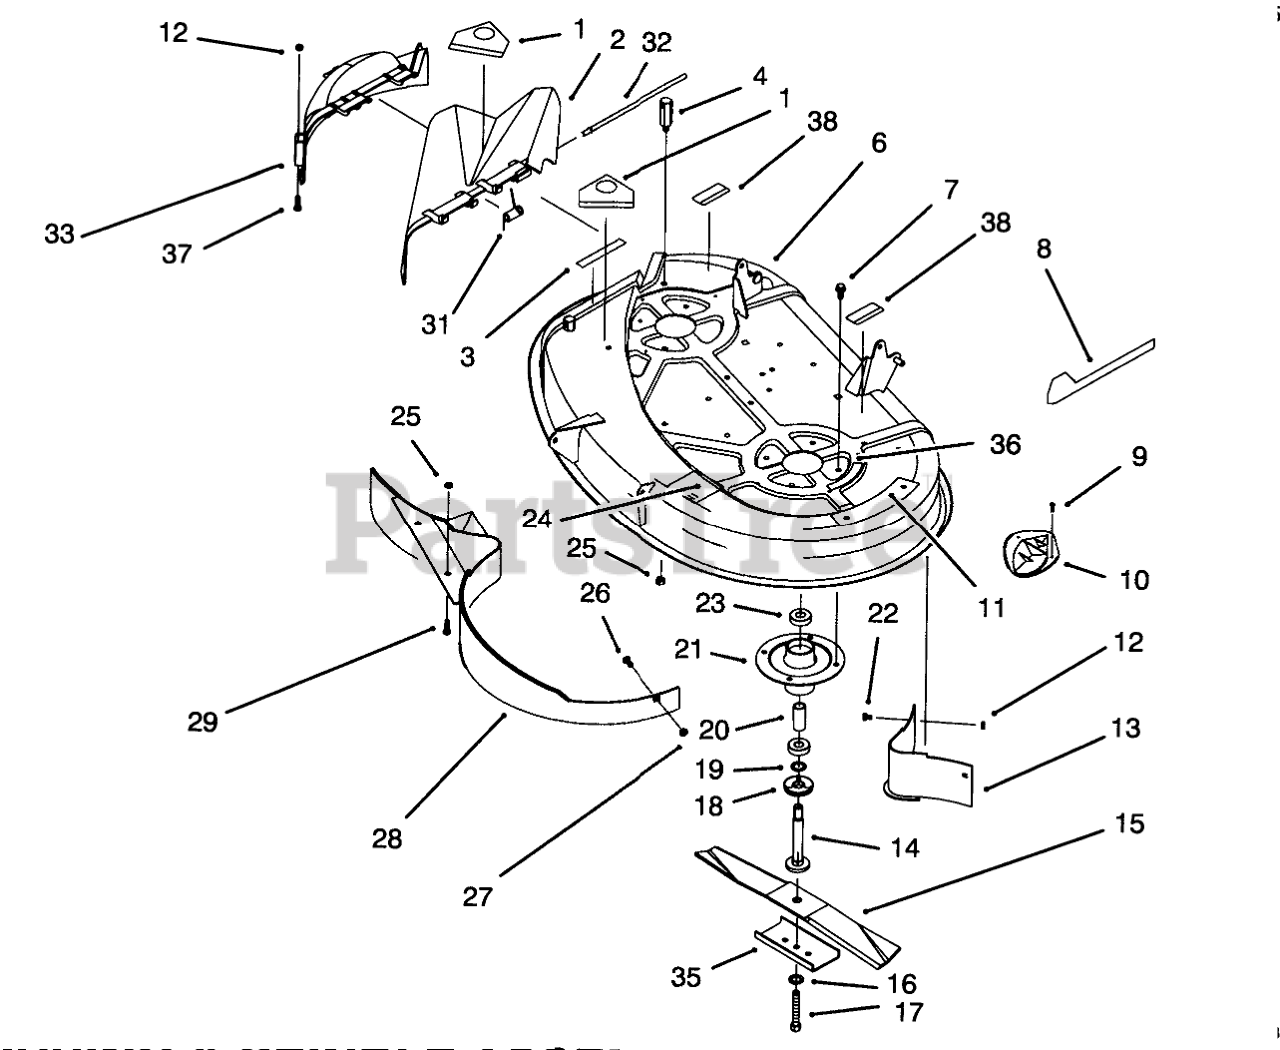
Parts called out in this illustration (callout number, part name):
1	DECAL-DANGER
2	Deflector-Deck
3	DECAL-DANGER, DEFLECTOR
4	REAR PIVOT POST (PLTD)
6	Deck-38"
7	SCREW-TAPTITE
8	DECAL-RECYCLER DECK 38"
9	SCREW-PPH
10	PLATE-KICKER
11	DECAL-DANGER
12	NUT-LOCK, NI
13	Baffle-Rear
14	SHAFT-SPINDLE
15	Blade
16	WASHER-BELLEVILLE
17	SCREW-HH
18	SHIELD-BEARING
19	SPACER
20	SPACER
21	HOUSING-SPINDLE
22	SCREW-HH
23	BEARING-BALL
24	Decal-Routing
25	NUT-LOCK, NI
26	BOLT-CARR
27	NUT-LOCK, NI
28	Baffle-38"
29	SCREW-HH
31	SPRING
32	ROD-HINGE DEFLECTOR
33	COVER-RECYCLER
35	Stiffener
36	DECAL-DANGER, SHIELD
37	SCREW-HH
38	DECAL-WARNING
